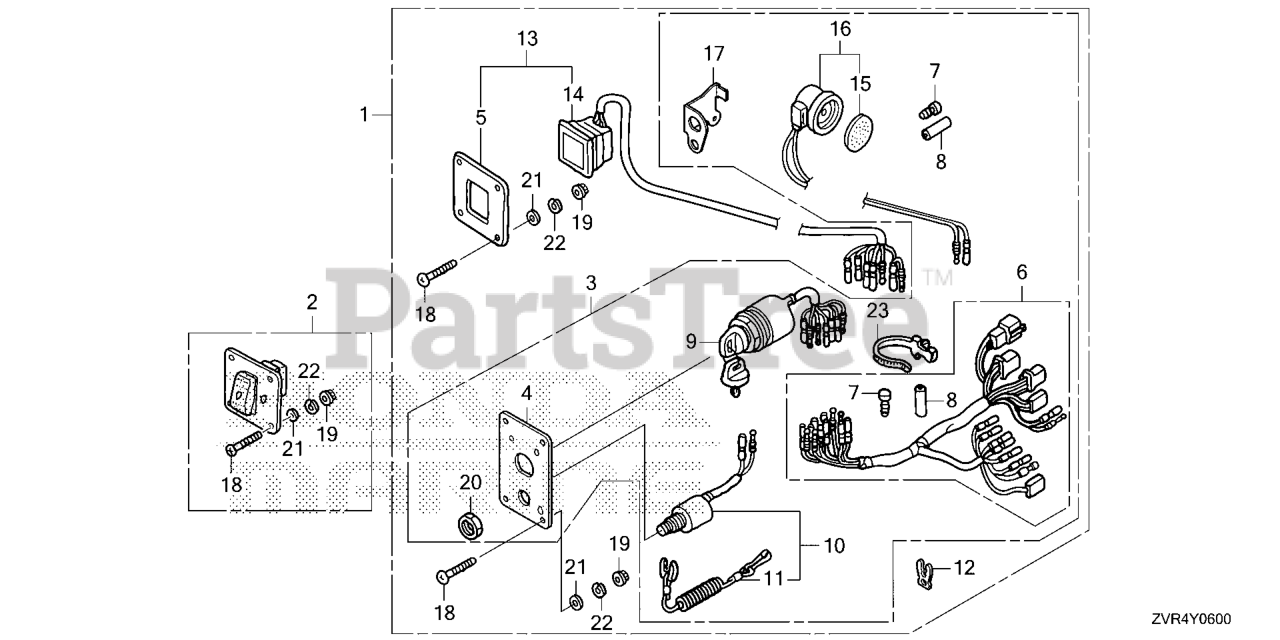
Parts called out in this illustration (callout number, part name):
1	PANEL KIT, SWITCH (4-LED) (B)
2	SW KIT, LIGHT
3	PANEL ASSY., SWITCH
4	PANEL, CONTROL
5	PANEL, CONTROL
6	HARNESS ASSY., SWITCH PANEL
7	PLUG, CONNECTOR (INNER) (TROLLING CONTROL)
8	PLUG, CONNECTOR (OUTER) (ENGINE NO.)
9	SWITCH ASSY., COMBINATION (SINGLE) (DUAL)
10	SWITCH ASSY., EMERGENCY STOP
11	WIRE, EMERGENCY (SINGLE) (DUAL)
12	CLIP, EMERGENCY LOCK
13	PANEL ASSY., INDICATOR (4-LED)
14	LAMP ASSY., INDICATION (4-LED)
15	PLATE, TURN SIGNAL BUZZER DUAL QTY = (2) (SINGLE)
16	BUZZER, WARNING DUAL QTY = (2) (SINGLE)
17	BRACKET, BUZZER
18	SCREW, PAN (5X40) DUAL QTY = (8) (SINGLE)
19	NUT, FLANGE (5MM)
20	NUT, HEX. (16MM) DUAL QTY = (2) (SINGLE)
21	WASHER, PLAIN (5MM)
22	WASHER, SPG (5MM)
23	BAND, WIRE HARNESS (150MM) (NATURAL) DUAL QTY = (2) (SINGLE)
